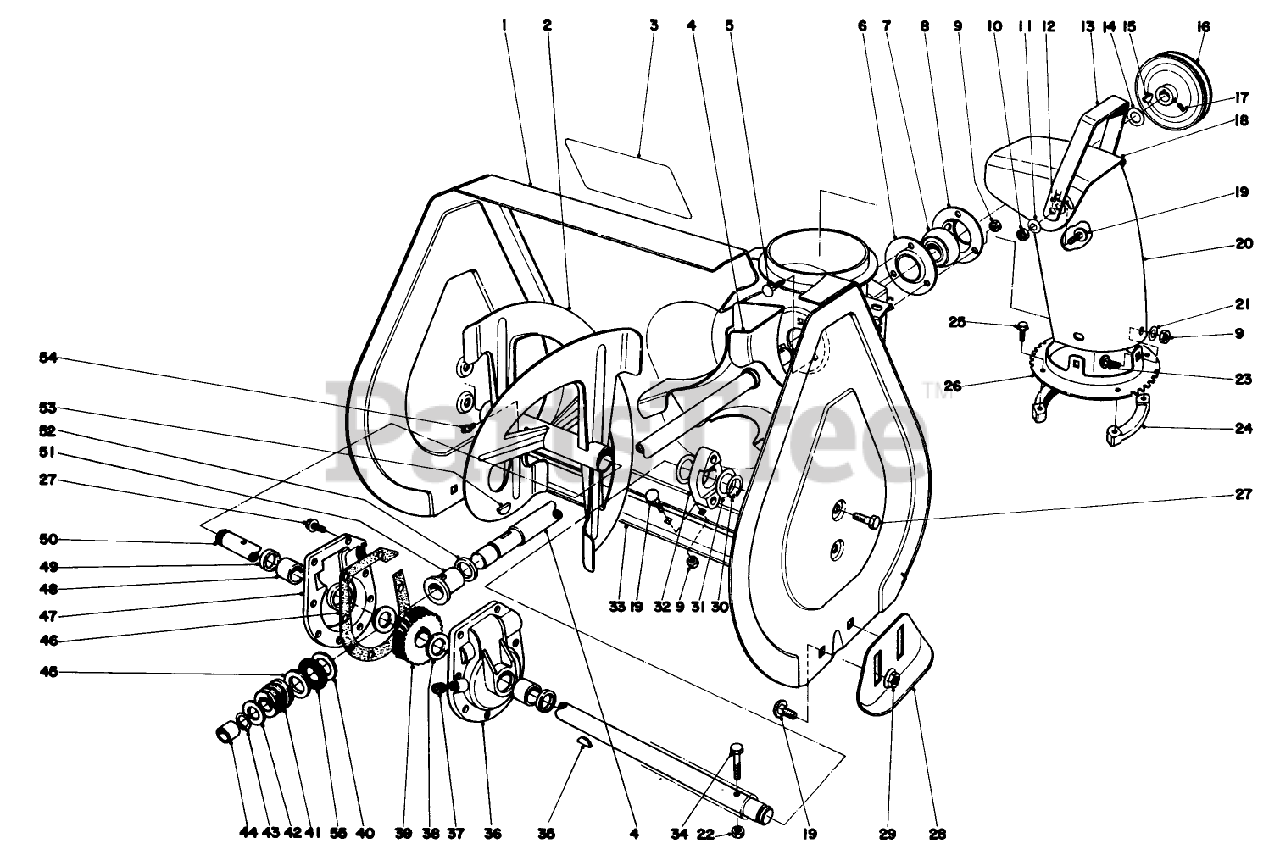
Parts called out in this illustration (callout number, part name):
1	Auger Housing
2	Auger L.H.
3	Decal-Warning
4	Shaft & Impeiler
5	BOLT-CARR
6	FLANGE-CUP, BEARING
7	Ball Bearing
8	FLANGE-CUP, BEARING
9	NUT-LOCK, NI
10	NUT-LOCK, CONE
11	WASHER-BELLEVILLE
12	WASHER-RUBBER
13	Handle Deflector
14	WASHER
15	KEY-WOODRUFF
16	PULLEY
17	Set Screw
18	Deflector
19	BOLT-CARR
20	Chute-Discharge
21	WASHER-PLAIN
23	SCREW-CARR
24	RING-CHUTE, RETAINER
25	SCREW-SPECIAL
26	Chute Ring
27	SCREW-HWHTF
28	Skid
29	NUT-HF
30	RING-RETAINING
31	WASHER
32	BEARING-AUGER
33	Scraper Blade
34	SCREW-HH
35	KEY-WOODRUFF
36	Gear Case R.H. (Incl. Ref. #48 & #49)
37	PLUG-PIPE, SQH
38	WASHER-THRUST
39	Gear
40	WASHER-THRUST
42	WASHER-THRUST
43	Ring-Snap
44	BUSHING
45	WASHER-THRUST
46	Gasket
47	Gear Case L.H. (Incl. Ref. #48 & #49)
48	BUSHING
49	SEAL-OIL
50	AUGER SHAFT
51	BUSHING-INPUT
52	RING-QUAD
53	KEY-WOODRUFF
54	FITTING-GREASE
55	BEARING-THRUST
